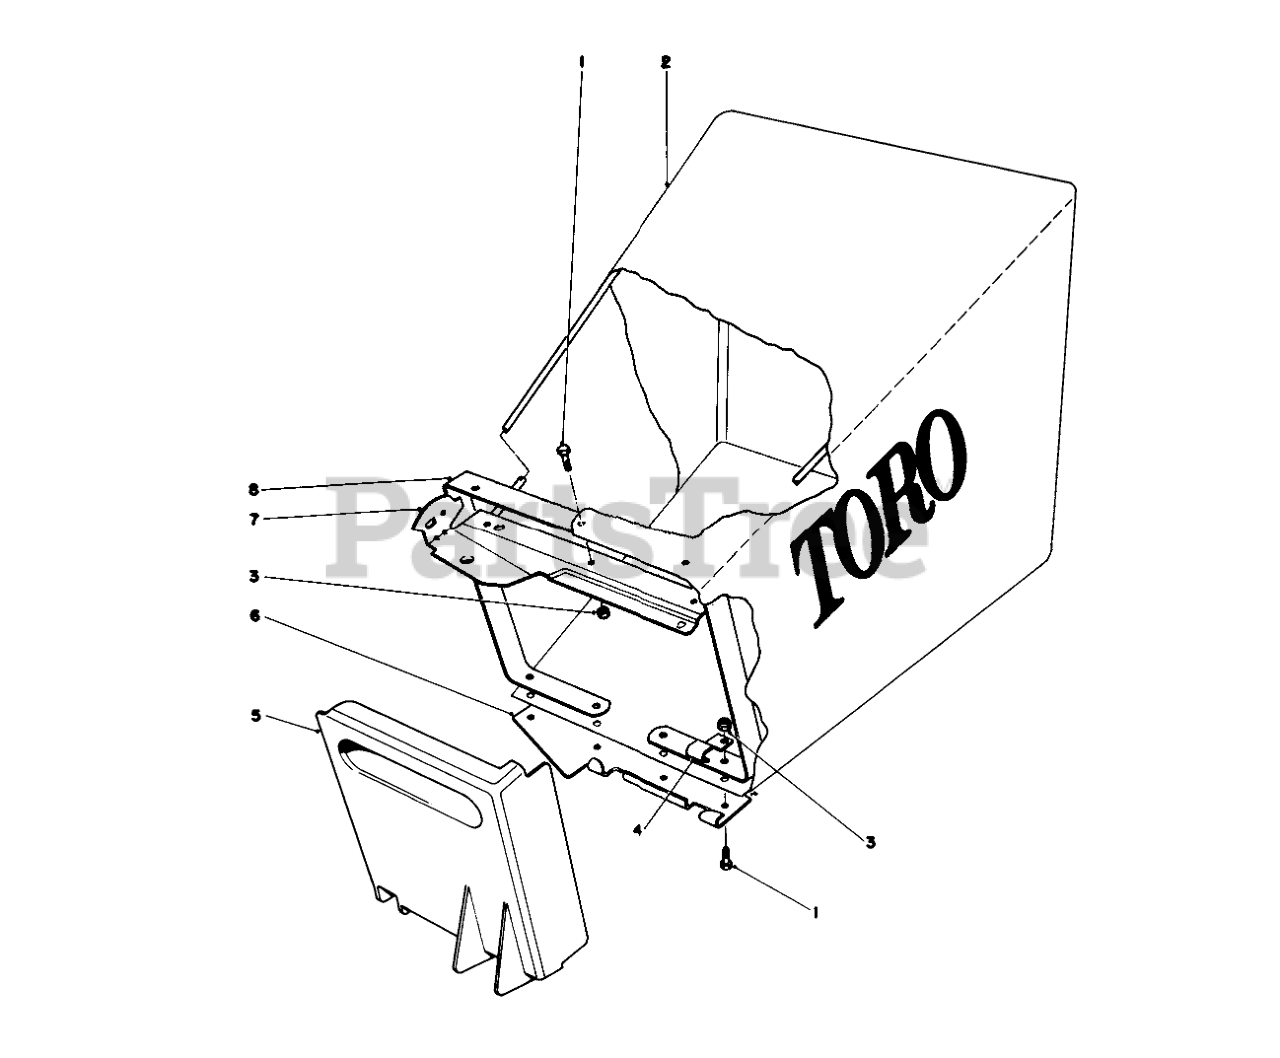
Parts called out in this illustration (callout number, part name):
1	216 Washer
2	REPLACMNT BAG 44-0530
3	NUT/WASHER
4	SUPPORT BRACKET
5	BAG DOOR
6	DOOR BRACKET
7	BAG FRAME WA
8	LOWER BAG FRAME
